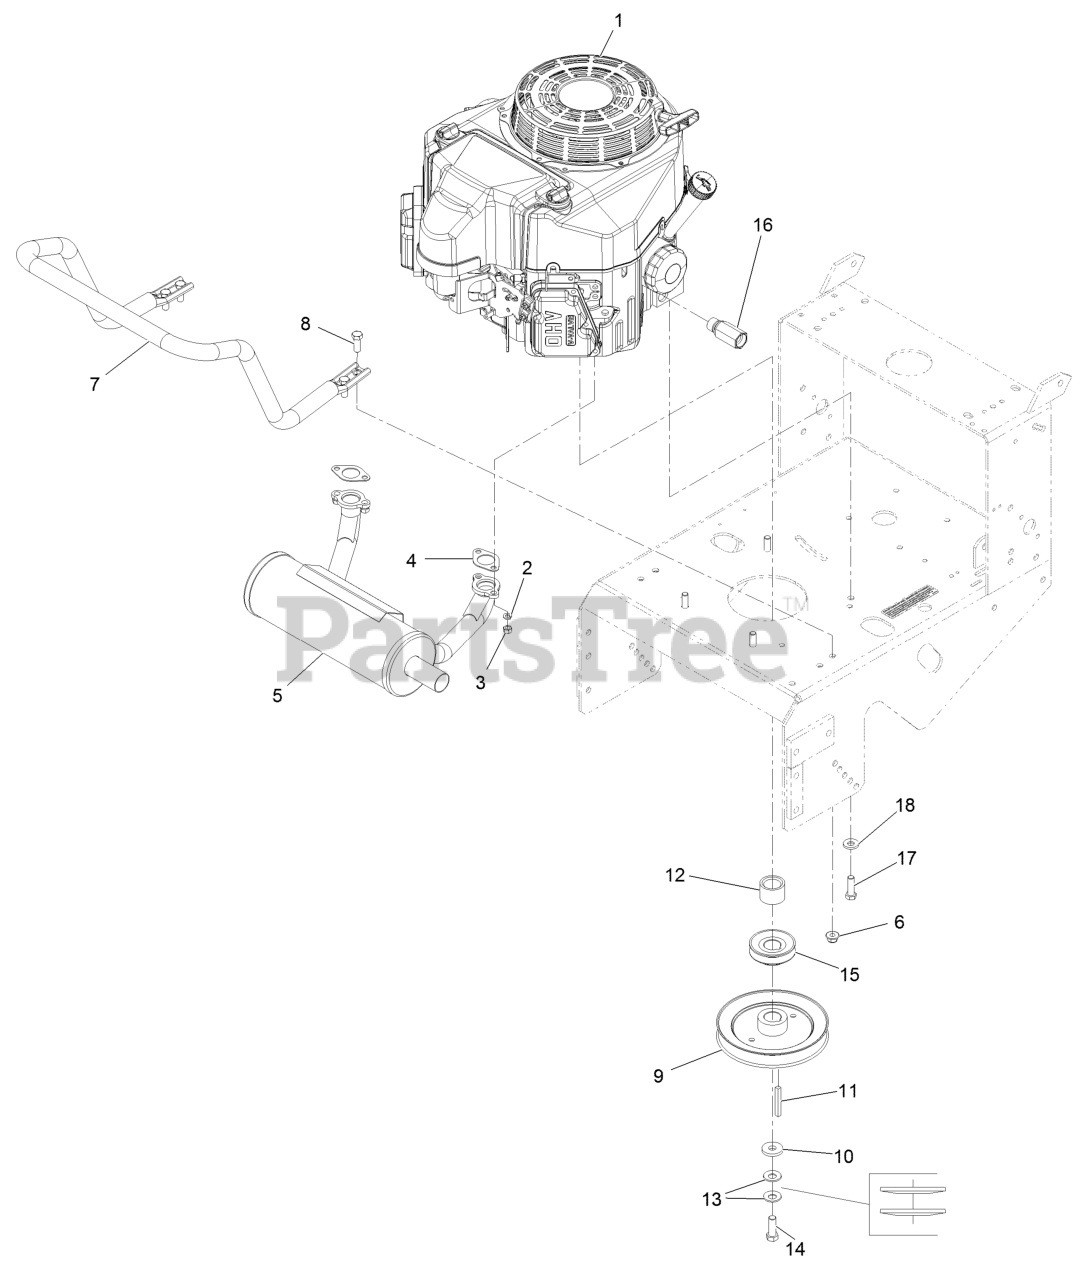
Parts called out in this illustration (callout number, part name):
1	Engine-Kawasaki
2	WASHER-LOCK
4	GASKET-EXHAUST
5	MUFFLER-HORIZONTAL, OFFSE
6	NUT-HF, NI
7	GUARD-MUFFLER
8	SCREW-HH
12	SPACER-CLUTCH
13	WASHER-SPRING
14	SCREW-HH
15	SHEAVE-TRANSMISSION
16	ADAPTER
17	SCREW-HH
18	WASHER-BELLEVILLE
